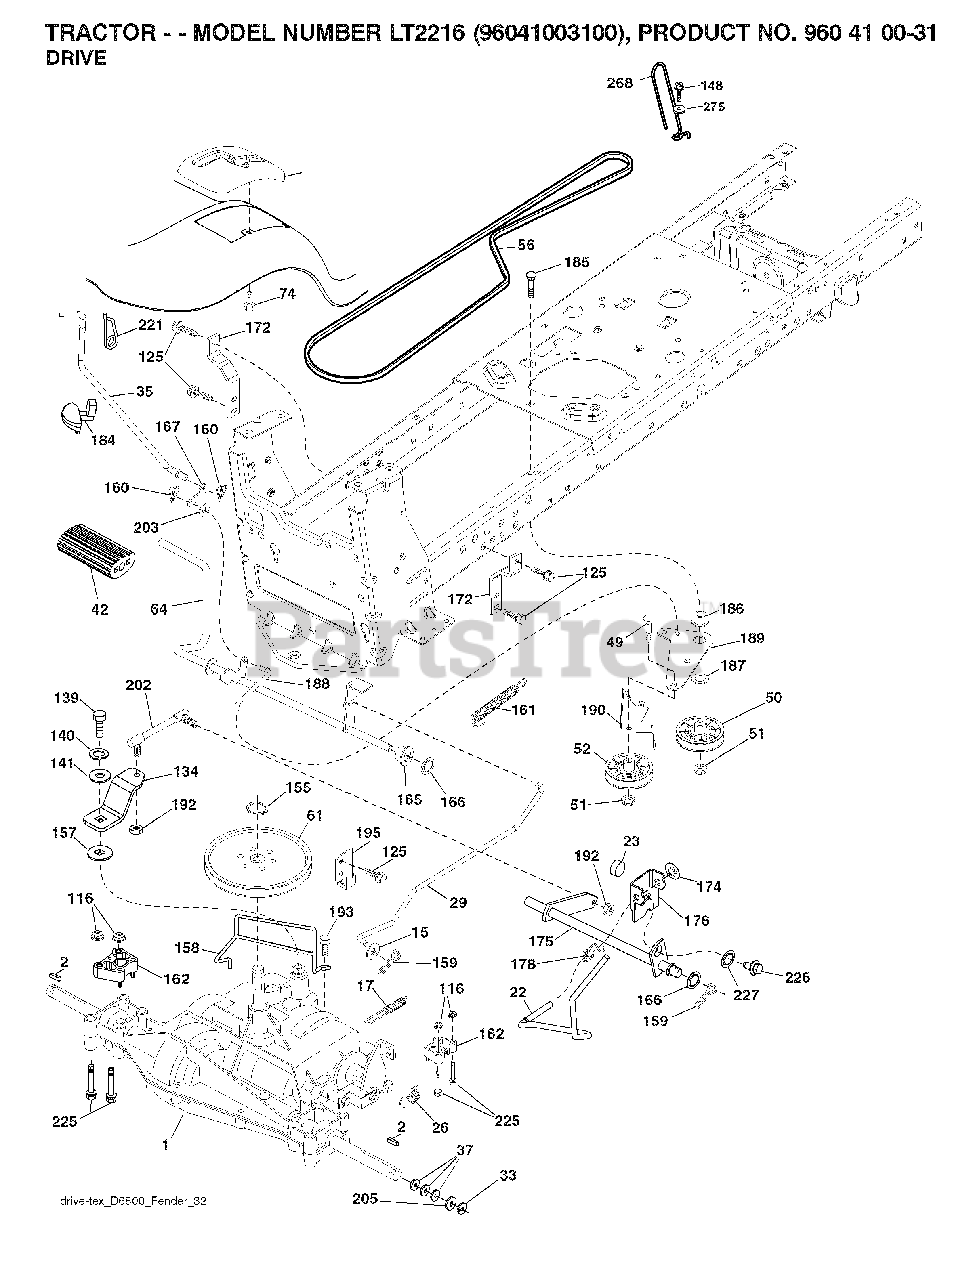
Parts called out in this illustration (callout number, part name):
2	SQUARE KEY
17	SPRING.BRAKE.PEERLESS.TEX
22	ROD.SHIFT.FENDER.TLT.2006
23	KNOB.DUCKHEAD.1/2
26	SPRING.BRAKE.RTN.GR.DR
29	ROD.BRAKE.PEERLESS
33	E-RING LT
35	ROD.BRAKE.PARKING.LT.T
42	PEDAL COVER T
49	BOLT
50	IDLER.FLAT.910.OFFSET
51	NUT LOCK FLG 3/8-16 UNC
52	IDLER.V-GROOVE.910.OFFSET
56	V-BELT.TRACTOR.DRIVE.P
61	PULLEY TRANS
64	SHAFT.ASM.PEDAL.BRAKE.
70	CONSOLE.SHIFT.
74	SCREW.HI-LO.CONSOLE
116	NUT LOCK HEX FLANGE 5/16-18
125	SCREW
134	ARM.SHIFT.
139	BOLT 1/4-28X3/4
140	LOCKWASHER
141	WASHER LT
148	SCREW, 3/8-16X3/4
155	RETAINING RING LT
157	WASH-SHFT PLT LT
158	KEEPER.PMS.18/20.D4365
159	COTTER PIN
160	RETAINER CLIP
161	SPRING.RETURN.CLUTCH.2006
162	SPACER.TRANSAXLE.18&22
165	BUSHING.SHAFT.BRAKE.HAND
166	NUT.PUSH.625.2006
167	LATCH.BRAKE.SPRING
172	STRAP.TRQ.LH.GEAR.DRIV
174	NUT.PUSH.500.2006
175	SHAFT.ASM.SHIFT.
176	ARM.CLEVIS.ROD.SHIFT
178	SPRING.SHIFT.GT2006
184	HANDLE.PAKRING.BRAKE.
186	SPACER.RETAINER
187	WASHER 12/32X2X10GA
188	LINK.CLUTCH.GROUND.DRIVE
189	BELLCRANK.GROUND.DRIVE.TEX.
190	KEEPER.BELLCRANK.DRIVE
192	NUT LOCK CENTER 1/4 -28 FNTHD
193	SCREW 5/16"
195	BRKT.ROD.BRAKE.PEERLES
202	LINK.TRANSAXLE.
203	WASHER
221	RETAINER.SPRING.CLIP.H
225	BOLT.HEX.FLNG.5/16-18X3.75
226	BOLT FIN HEX 7/16-14 X 1
227	WASHER SERRATED
268	WASHER
